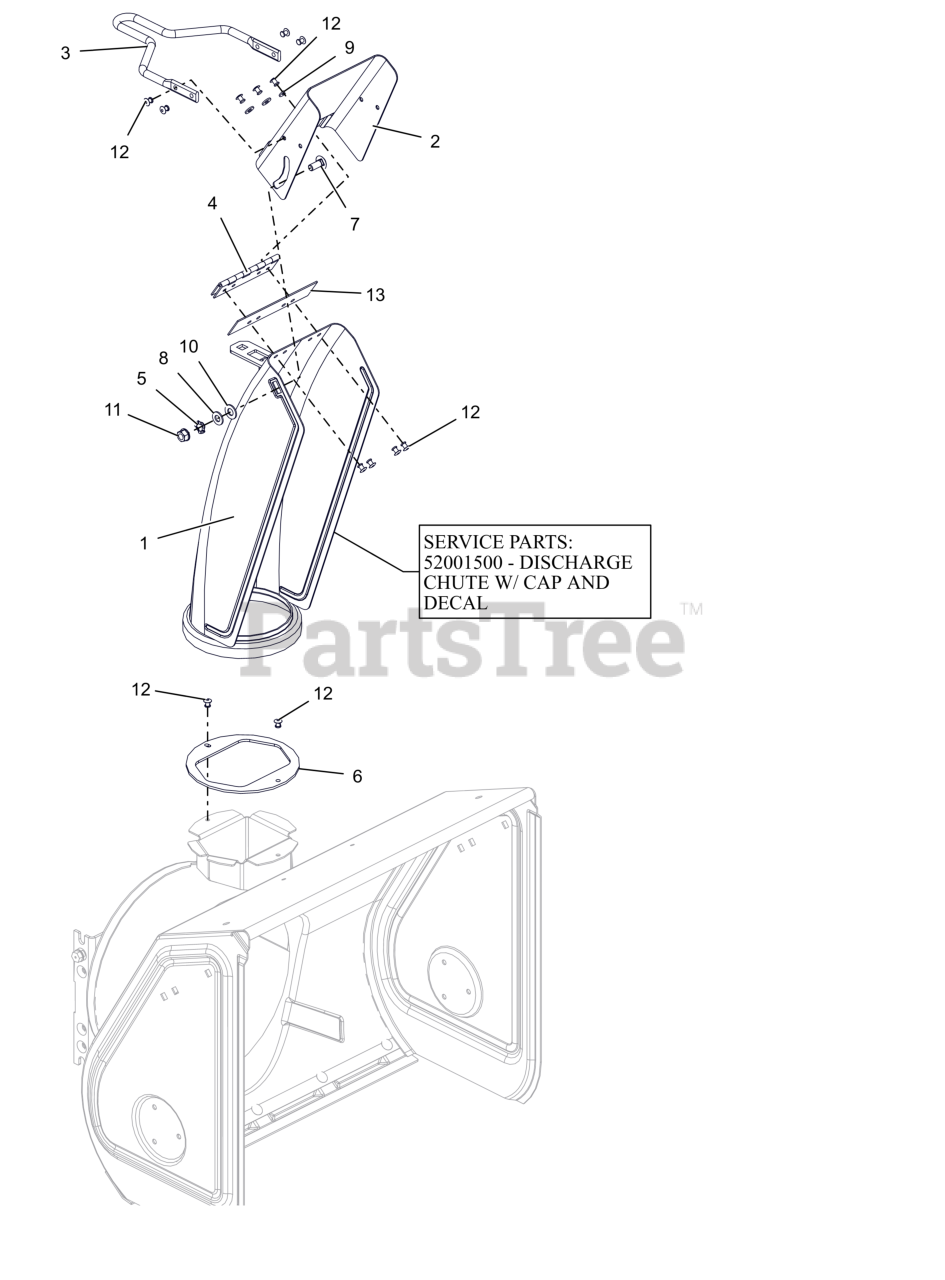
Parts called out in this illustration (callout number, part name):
1	CHUTE, COMPACT - TALL
1	CHUTE, DISCHARGE W/CAP & DECAL
2	CAP,MANUAL - COMPACT (W/DECAL)
3	LEVER, DEFLECTOR CAP (BLACK)
5	WAVE WASHER .390X.655X.110
6	BAFFLE, COMPACT DISCHARGE
7	BLT, RHSSN.31-18X.750 G5 ZCC
8	WSHR,FLT .344X.688X.065 ZCC
9	WSHR,FLT .196X.500X.066 ZCC
10	WSHR-FL-NY .375X.75X.060
11	NUT,LK-CTR-FLG .31-18 GF ZCC
12	RVT, POP .1875 ZCC
13	CAP SEAL 5.50
